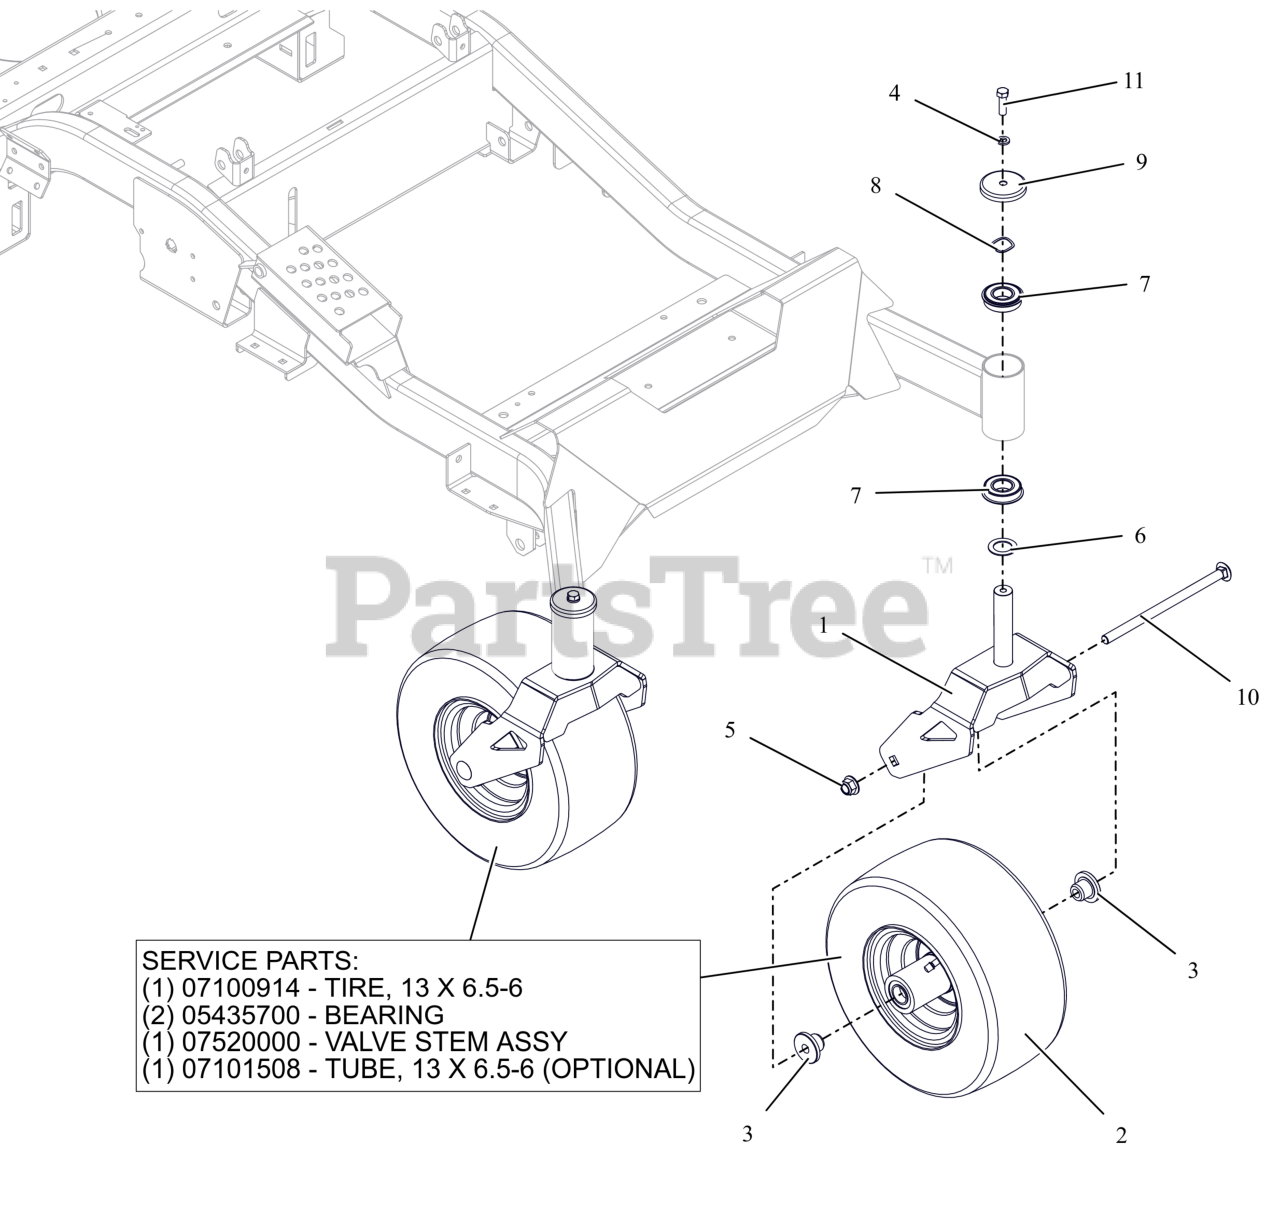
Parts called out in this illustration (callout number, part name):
1	WLDMT, CASTER FORK-HD (ORANGE)
2	ASM, TIRE/WHEEL 13 X 6.50-6 BLK RIM
2	LAWN TIRE FRONT, 13X6.50-6 SMOOTH
2	BRG, 25MM ID X 52MM OD X 15MM
2	VALVE STEM ASS'Y
2	TIRE TUBE, 13/6.5-6 4 PLY TR87 90 BENT VALVE
3	SPACER, FRONT WHEEL
4	WSHR-LK-REG .375X.094 ZB500
5	NUT,NYL-FLG .50-13 GF ZCC
6	WSHR-HRD-THRS 1.007X1.542X.062
7	BEARING, BALL -2.000 OD X 1.000 ID X .5625 W/RING
8	WSHR-WAVE 1.0X1.25X.028 .145FH
9	SHIELD, AXLE BEARING
10	BLT, RHSN .50-13X9.00 G5 ZCC
11	BLT- HEX .38-16X1.25 G5 ZB500
